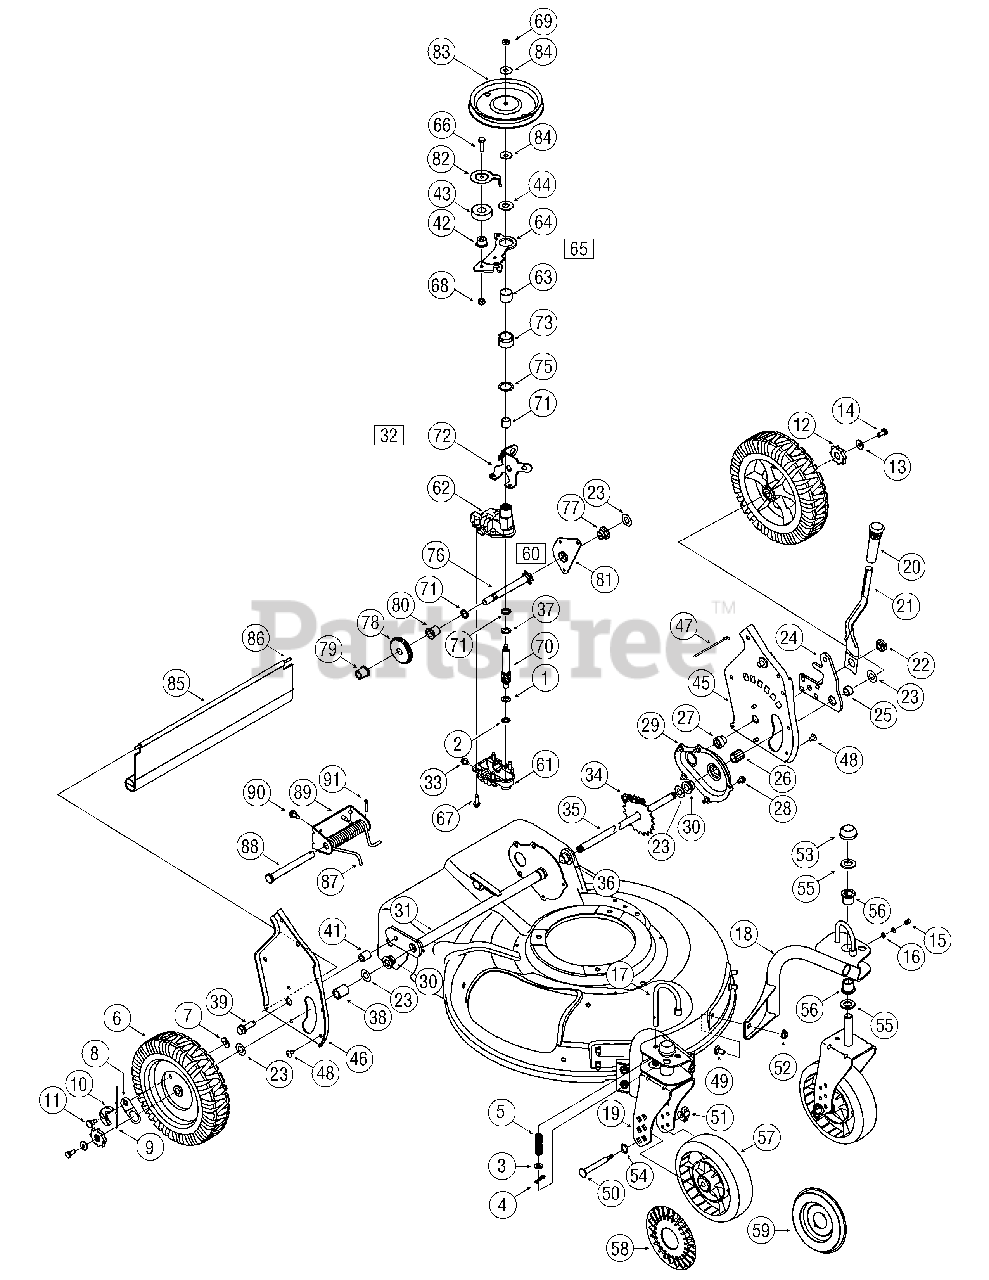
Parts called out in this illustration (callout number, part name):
1	Thrust Washer 3/8 x .70
2	Thrust Washer .388 x .625
3	Flat Washer.330 ID x.630 OD
5	Compression Spring
6	Wheel 9 x 2
7	Top Lock Tab Weld Nut 1/4-20
8	Ratchet Pawl Plate
9	Plastic Spring Ratchet
10	Pawl LH
11	Shlder Screw.340 ID x.285 OD
12	Wheel Ratchet
13	Bell Washer.265 ID x.75 OD
14	Hex Cap Screw 1/4-20 x.620
15	Grease Fitting
16	Flat Washer.203 ID x.403 OD
17	Wheel Pin Lock
22	Shoulder Nut.825 x .165 Lg.
23	Flat Washer .508 ID x 1.0 OD
25	Spacer .510 ID x .70 OD
26	Slv Bearing .504 ID x .830 OD
27	Shlder Spacer, .385ID x .715Lg
28	Tap Screw 1/4-20 x .375
32	Transmission Ass’y Complete
33	Hex Screw 5/16-18
34	Chain
35	Rear Axle Assembly
36	Flge Bearing .506 ID x .715 Lg
37	Flat Washer .885 ID x 1.45 OD
38	Spacer .550 ID x .750 OD
39	Screw 3/8-16 x .25
42	Flange Spacer
43	Bearing
44	Flat Washer .510 ID x 1.120 OD
48	Screw 1/4-14 x.500
49	Carriage Bolt 5/16-18 x.62
50	Caster Axle
51	Wing Nut
52	Flange Lock Nut 5/16-18
54	Wave Washer.531 ID x.781 OD
55	Flat Washer.640 ID x 1.12 OD
56	Flange Bearing
58	Hubcap - Spoke w/ Hole
59	Hubcap - Radial Spoke
60	Shaft Assembly
61	Lower Housing Assembly
62	Upper Housing Assembly
63	Spacer .915 x 1.125 x .762
64	Idler Bracket
65	Idler Bracket Assembly
66	Hex Cap Screw 1/4-28 x 1.0
67	Hex Screw 1/2-20 x .75
68	Hex Jam Nut 1/4-28
69	Hex Jam Nut 5/16-24
70	Pinion Shaft 10T
71	Oil Seal
72	Extension Spring
73	Bearing Sleeve
75	Thrst Washer .504 ID x .70 OD
76	Output Shaft 6T
77	Flange Bearing
79	Flange Bearing
80	Flange Bearing
81	Pivot Bracket
84	Bell Washer .325 ID x .930 OD
86	Trail Shield Wire
87	Torsion Spring
88	Clevis Pin .50 Dia x 4.82 Lg.
